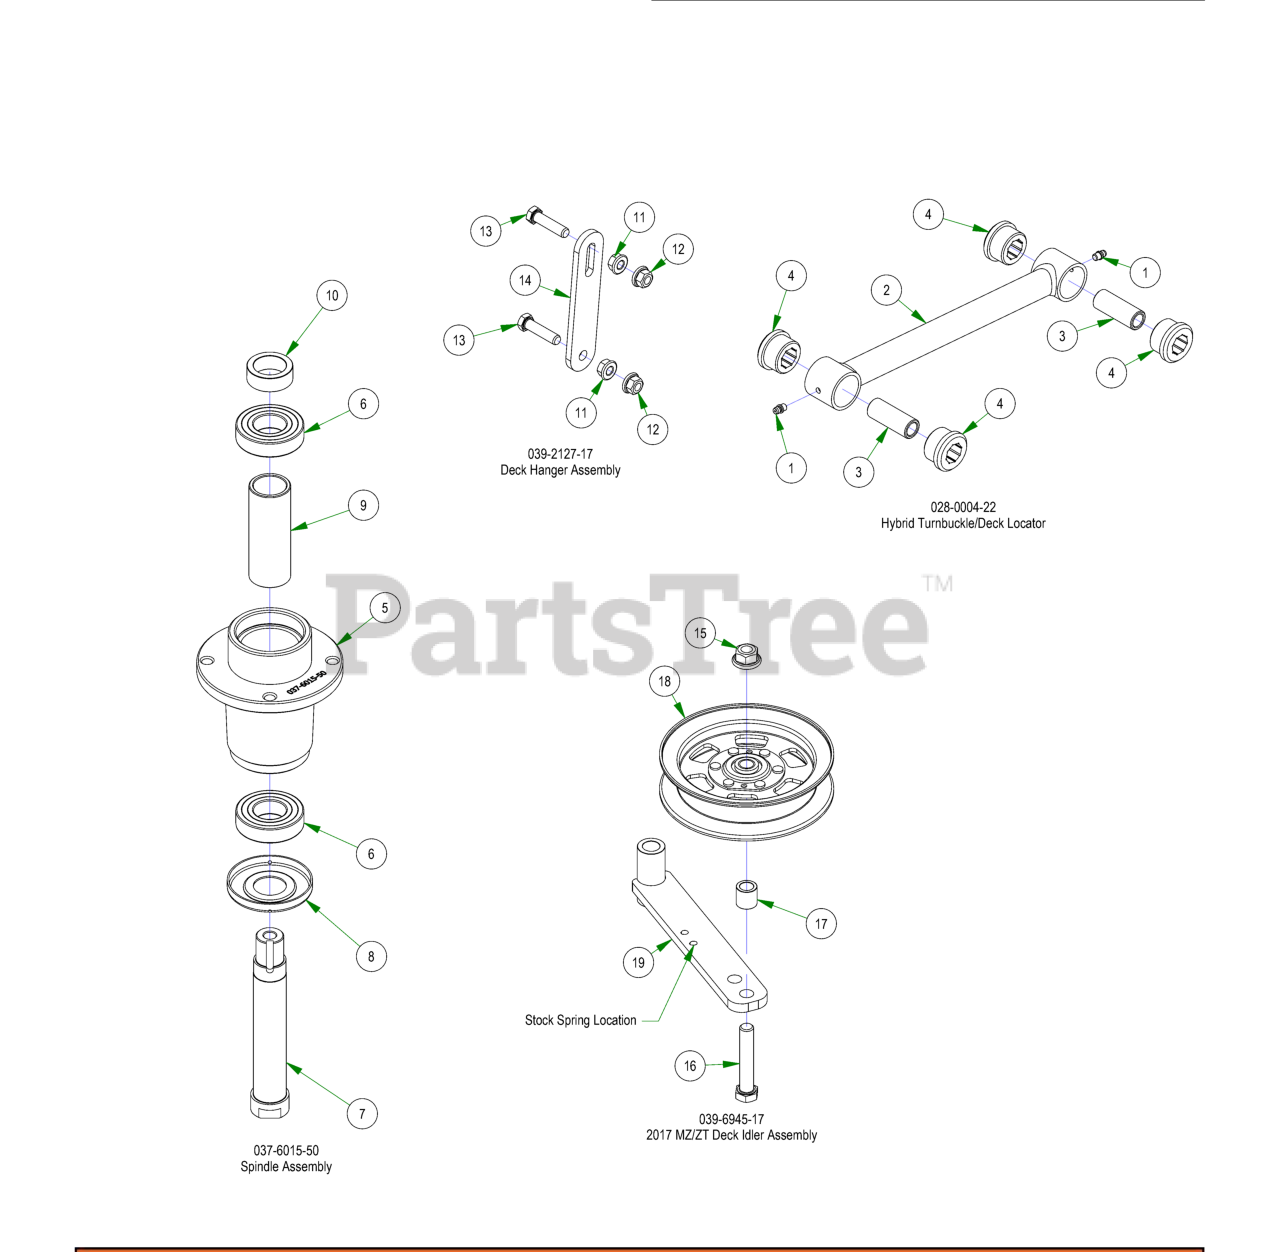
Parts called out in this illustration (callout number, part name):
1	1/4-28 Grease Fitting
2	2022 Isolator Turnbuckle Body
3	2018 Maverick Bushing Sleeve
4	2018 Maverick Bushing
5	Spindle Housing
6	Bearing - 6206
7	Spindle Shaft
8	Spindle Dust Cap
9	Spindle Spacer
10	Locking Collar w/ 1/4"-20 Set Screw
11	3/8-16 HEX SERRATED FLANGE NUT HARD/ZINC
12	3/8-16 NYLON INSERT FLANGE LOCKNUT (GR.F) ZINC
13	3/8-16 X 1-1/2 HEX CAP SCREW (GR.5) ZINC
14	2017 MZ/ZT Deck Hanger
15	1/2-13 NYLON INSERT FLANGE LOCKNUT ZINC
16	1/2-13 X 2-3/4 HEX CAP SCREW (GR.5) ZINC
17	Spacer 3/4 OD x 1/2 ID x 3\4 Length
18	5" Idler Pully
19	Deck Idler
